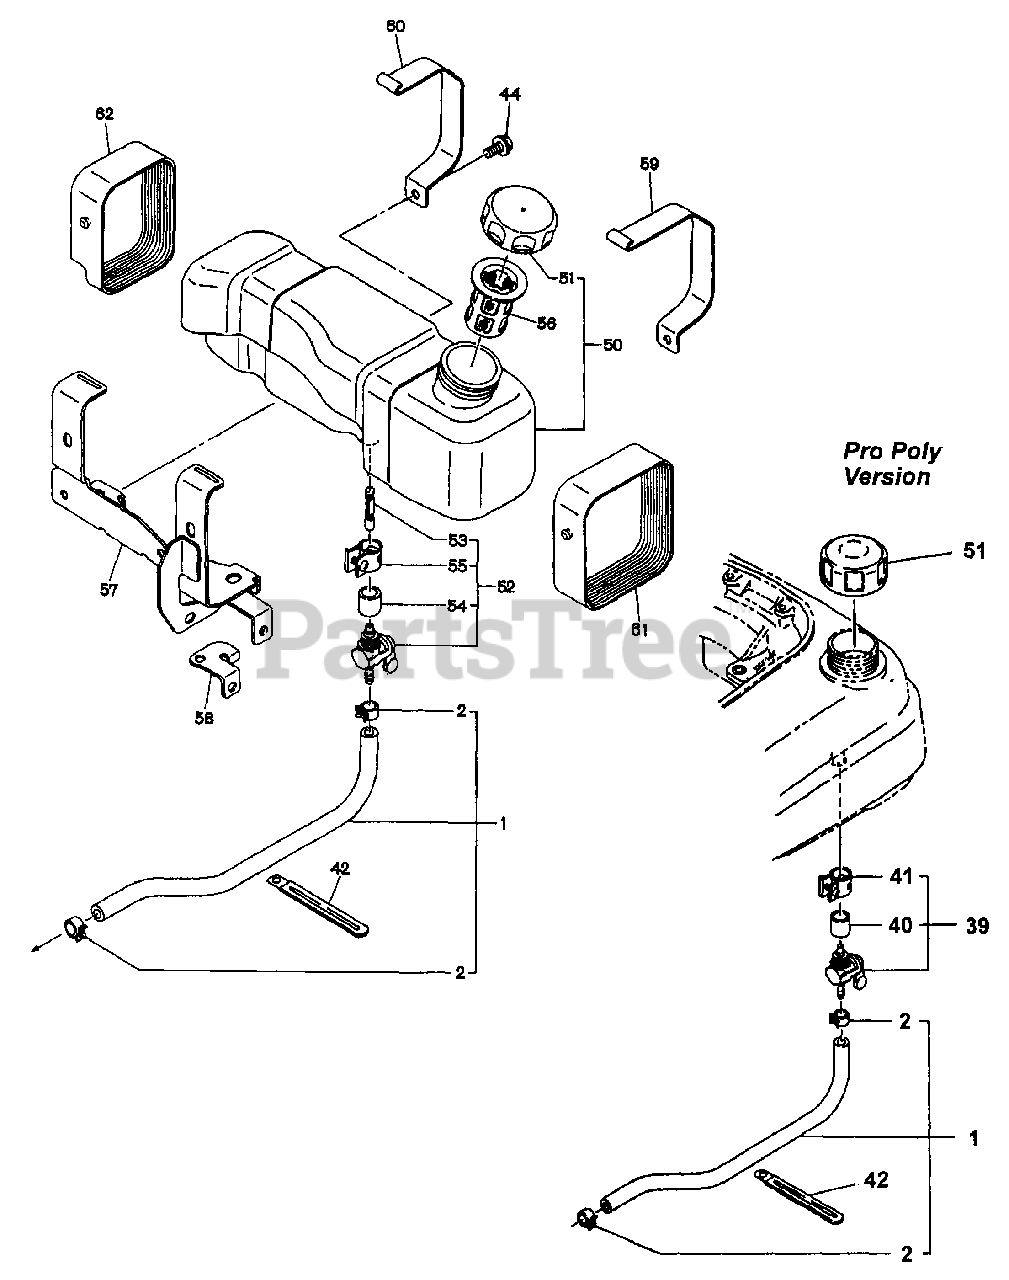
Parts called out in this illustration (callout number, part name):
1	FUEL PIPE, compl.
1	RUBBER PIPE (6ø x 12ø X 400mm)
39	FUEL COCK ASS'Y
41	HOSE BAND ASS'Y
44	FLANGE BOLT
50	FUEL TANK, compl.
51	FUEL TANK CAP, compl.
52	FUEL STRAINER ASS'Y
55	HOSE BAND ASS'Y
56	FUEL FILTER
57	FUEL TANK BRACKET, compl.
58	BRACKET, fuel tank
59	TANK BAND 1
60	TANK BAND 2
